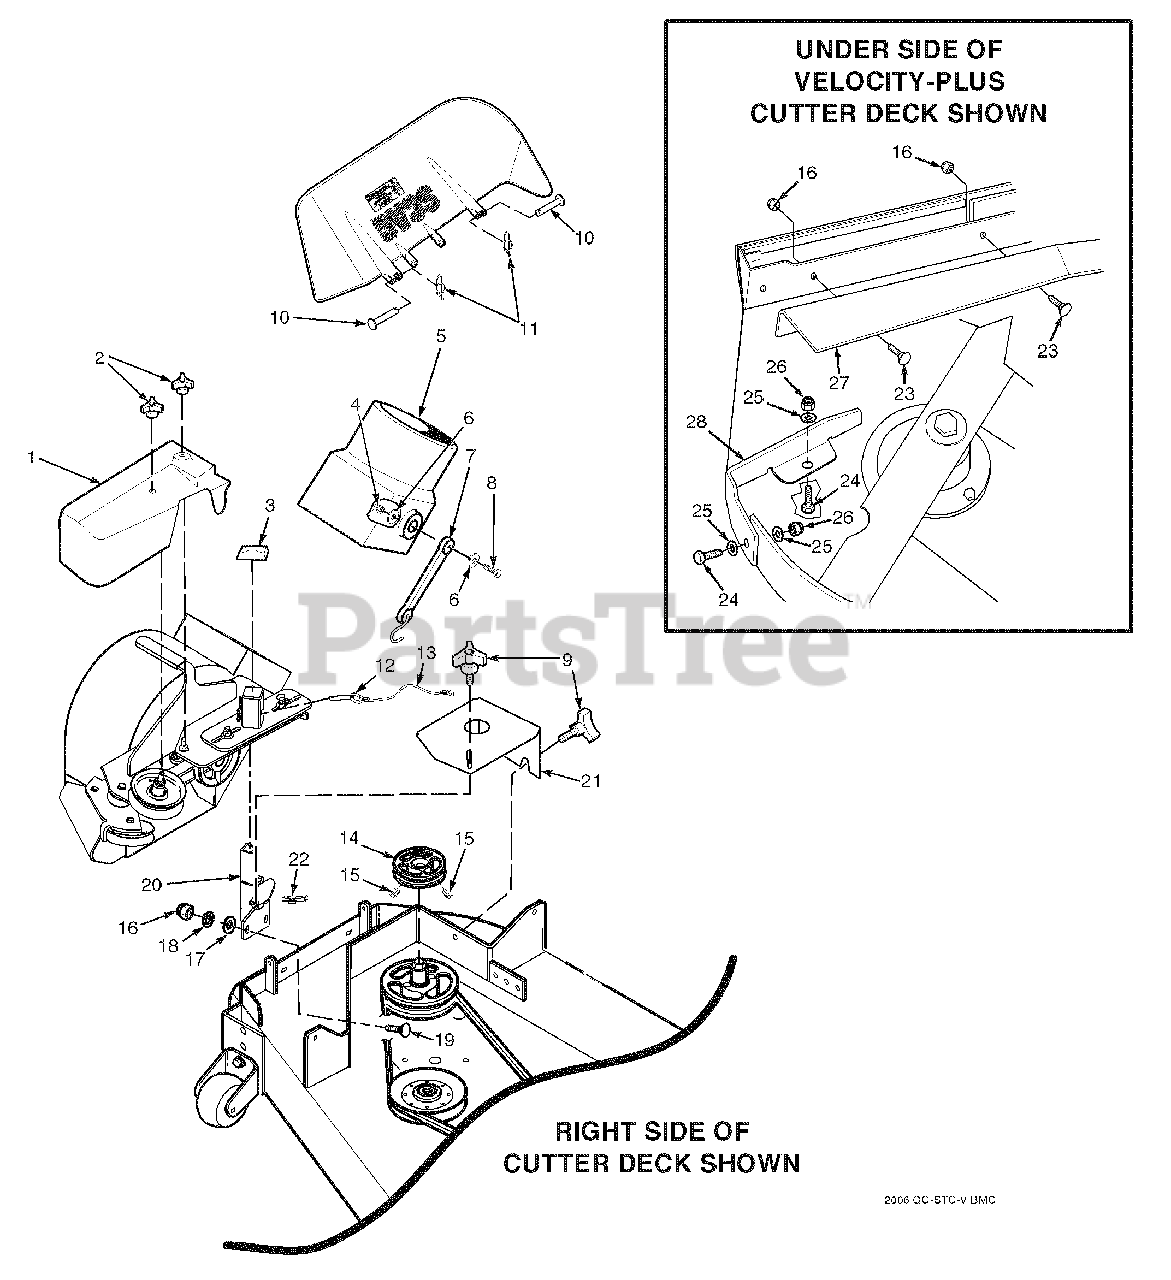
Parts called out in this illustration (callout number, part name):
1	Belt Cover, GC-61V
2	Wingnut, Plastic 3/8" Small
3	Cap, Square Vinyl
4	Nut, Elastic Stop 1/4-20
5	Adapter, Blower
6	Flatwasher, 1/4-.312 x .750 x .065
7	Rubber Strap 7-3/4"
8	Bolt, Hex Head 1/4-20 x 1-1/4"
9	Knob W/Stud, 3/8-16 x 1-1/4"
10	Clevis Pin, 5/16 x 1-1/2"
11	Pin, Rue Cotter 5/16 Dia.
12	Pin, Ring 1/2 x 2-1/4"
13	Lanyard
14	Pulley, 5-1/2" Dia. 1.125 Bore
15	Setscrew, 5/16-18 x 3/8"
16	Nut, Elastic Stop 3/8-16
17	Lockwasher, 3/8"
18	Flatwasher, 3/8-.391 x .938 x .105
19	Bolt, Carr. 3/8-16 x 1-1/4" Grade 5
20	Mounting Post Weldment, Blower
21	Belt Cover, GC-61V
23	Bolt, Carriage 3/8-16 x 1"
24	Bolt, Hex Head 5/16-18 x 1"
25	Flatwasher, 5/16-.375 x .875 x .083
26	Nut, Elastic Stop 5/16-18
27	Baffle, Front 61" Deck
28	Baffle, Turbo 61" Deck
